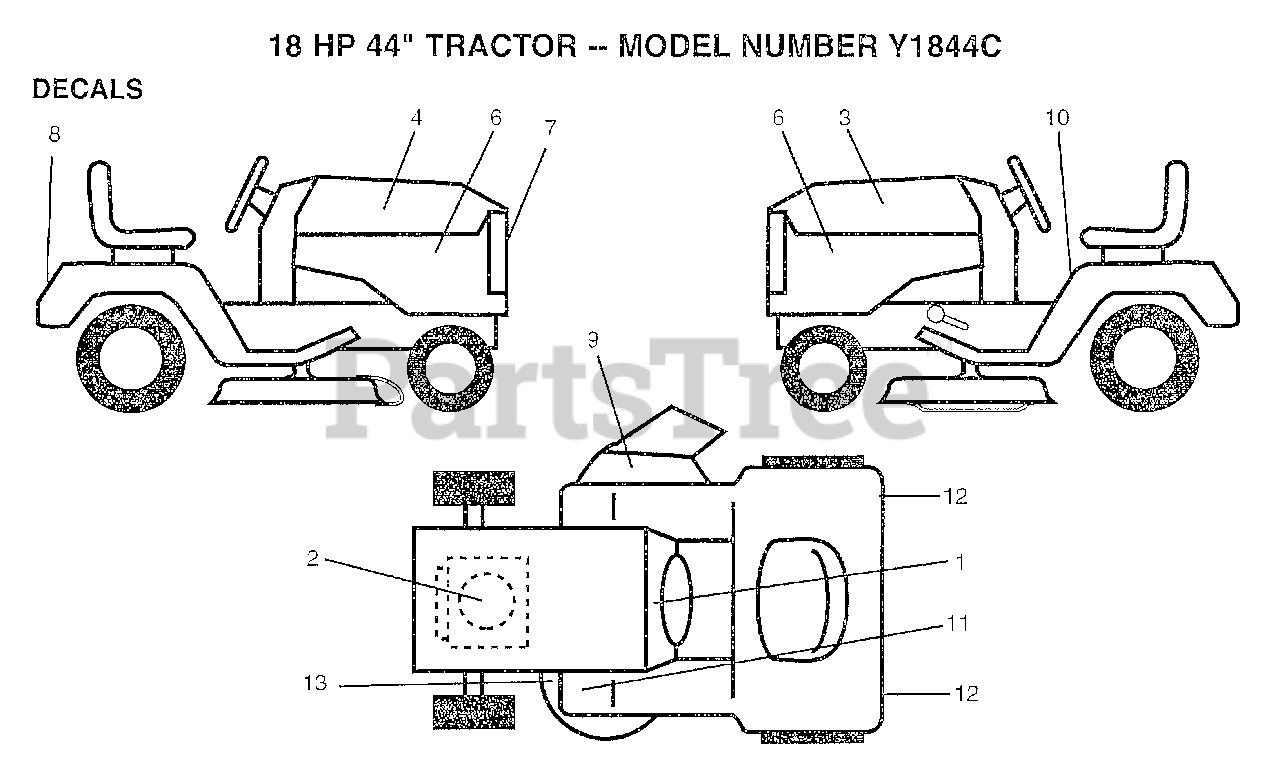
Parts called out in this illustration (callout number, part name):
1	DECAL.DASH.INSTR.
2	"DECAL,HP ENGINE"
3	DECAL HOOD LH
6	DECAL.PANEL.SIDE
7	DECAL.GRILL.YARDP
9	"DECAL, WARNING"
10	DECAL CAUTION
11	DECAL T
12	REFLECTOR-TAIL YT
